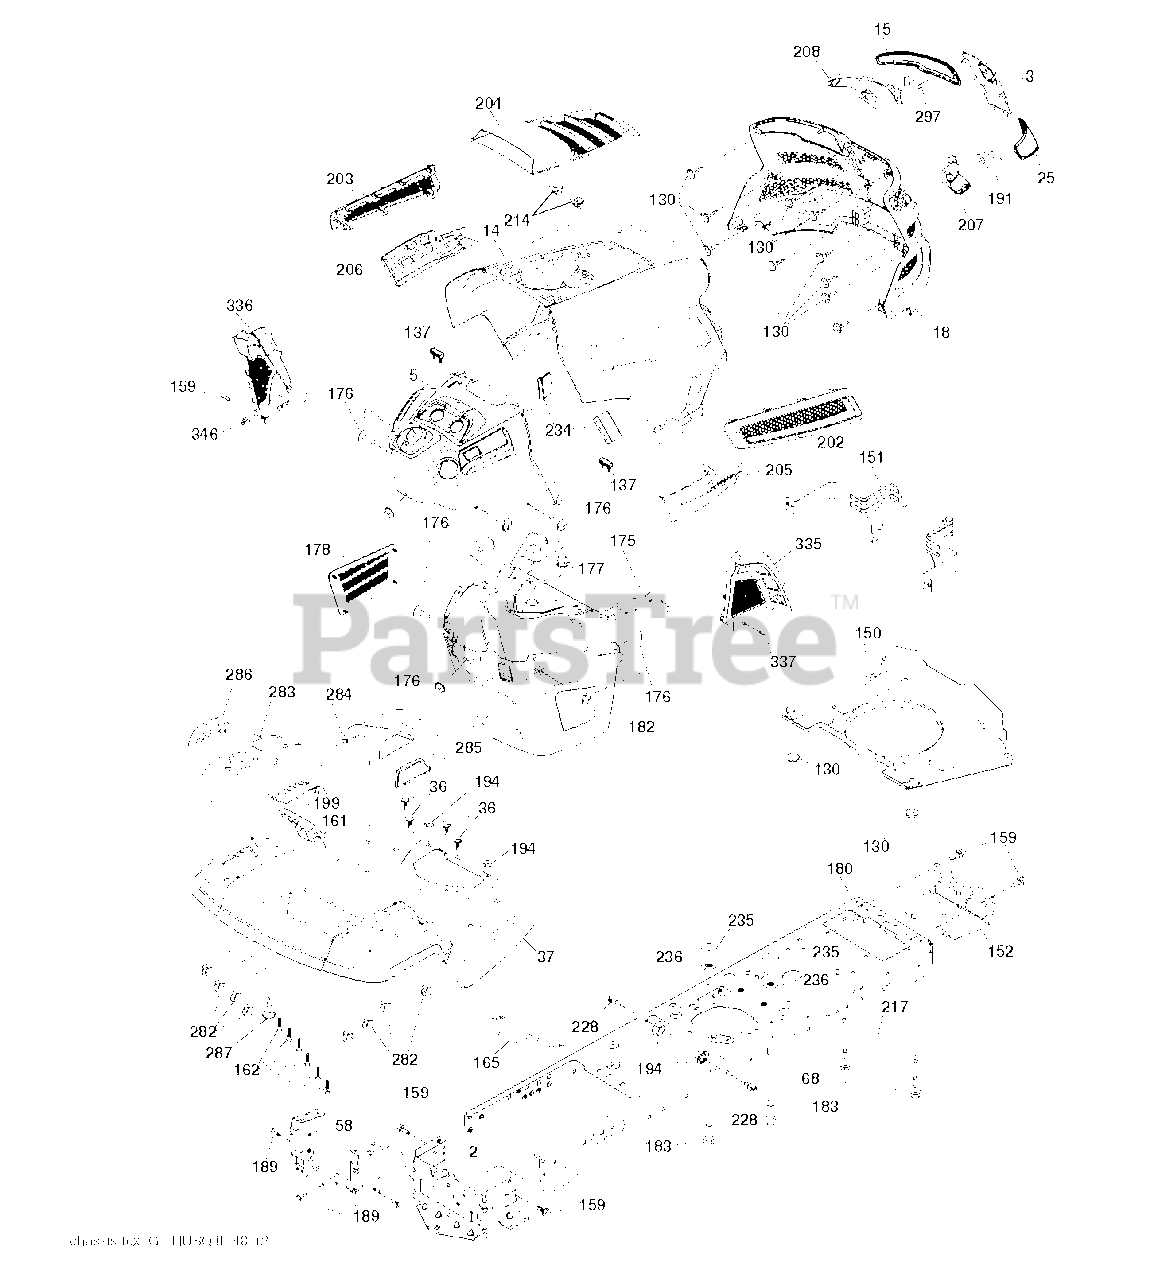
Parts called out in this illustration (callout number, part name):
2	DRAWBAR.LOWER.2PC.18/22
3	APPLIQUE.SUBASM.GT.HUSQ.II
5	DASH.UPPER.ASSY.GT2.DUAL
14	HOOD.ASM.HUSQVARNA.GT.TEX.422
15	LENS.HEADLIGHT.LH.GTII.2011
18	GRILLE.SUBASM.GT.HUSQ.II
25	LENS.HEADLIGHT.RH.GTII.2011
36	SCREW 5/16"
37	FENDER.TLT.FS.W/CPH/FW/RSF.ORN
58	DRAWBAR UPPER 2PC SMALL FENDER
68	SCREW LT
130	SCREW.#10 X 0.750.BOS
137	BUMPER DASH
150	AIR.DUCT.GTV.BLACK
151	BRACKET.PIVOT.HOOD.GT.HUSQ.II
152	SHIELD.BROWNING.PNT.GT.V2
159	SCREW, 3/8-16X3/4
161	WINDOW.FUEL.LT.HUSQ.TEX.498
162	SCREW.HI-LO.CONSOLE
165	SUPPORT.TANK.REAR.B/TE
175	PLATE.CROSSMEMBER.HUSQ
176	SCREW.#10-24X5/8.RN.QU
177	BUSHING, STEERING
178	CARGO.ASM.NET.TXGT.W/C
180	CHASSIS.STAMPING.LT/GT
182	DASH.LOWER.COMMON.12V.ADAPTOR
183	BOLT.5/16-18X1-1/4 FULL THD
189	SCREW
191	INSERT.REFLECTIVE.RH.HUSQ.GTII
194	NUT LOCK HEX FLANGE 5/16-18
199	PLATE.DECK.LIFT.HUSQ.LT
202	VENT.SIDE.RH.GT.HUSQ.II.
203	VENT.SIDE.LH.GT.HUSQ.II.498
204	VENT.TOP.HUSQ.GT2
205	SIDE.TRIM.RH.GT.HUSQ.II
206	SIDE.TRIM.LH.GT.HUSQ.II.GRAY
207	BEZEL LIGHT.RH.GT.II.MYLAR
208	BEZEL LIGHT.LH.GT.II.MYLAR
214	CLIP.RETAINER.TINNER.
217	ROD.PIVOT.HOOD
228	STUD.FASTNER.W/ANTI-ROTATE
234	BUMPER.HOOD.TEX.HUSQVARNA
235	SPACER FENDER
236	NUT.CENTERLOCK.5/16-
282	CLIP.RETAINER.CONSOLE.LT.HUSQ
283	CONCOLE.CNTRL.PDL.HUSQ.LT.498
284	CONSOLE.DECK.LIFT.R.SDFL.HUSQ
285	CONSOLE INSERT RH
286	CONSOLE.INSRT.LH.HUSQ.LT.BLACK
287	SCREW 1/4X20
297	INSERT.REFLECTIVE.LH.HUSQ.GTII
335	COVER.RH.CLOSE.OUT.BLACK
336	COVER.LH.CLOSE.OUT
337	CLIP.XMAS.TREE.ITW.2622-00
346	CLIP,INSULATOR
